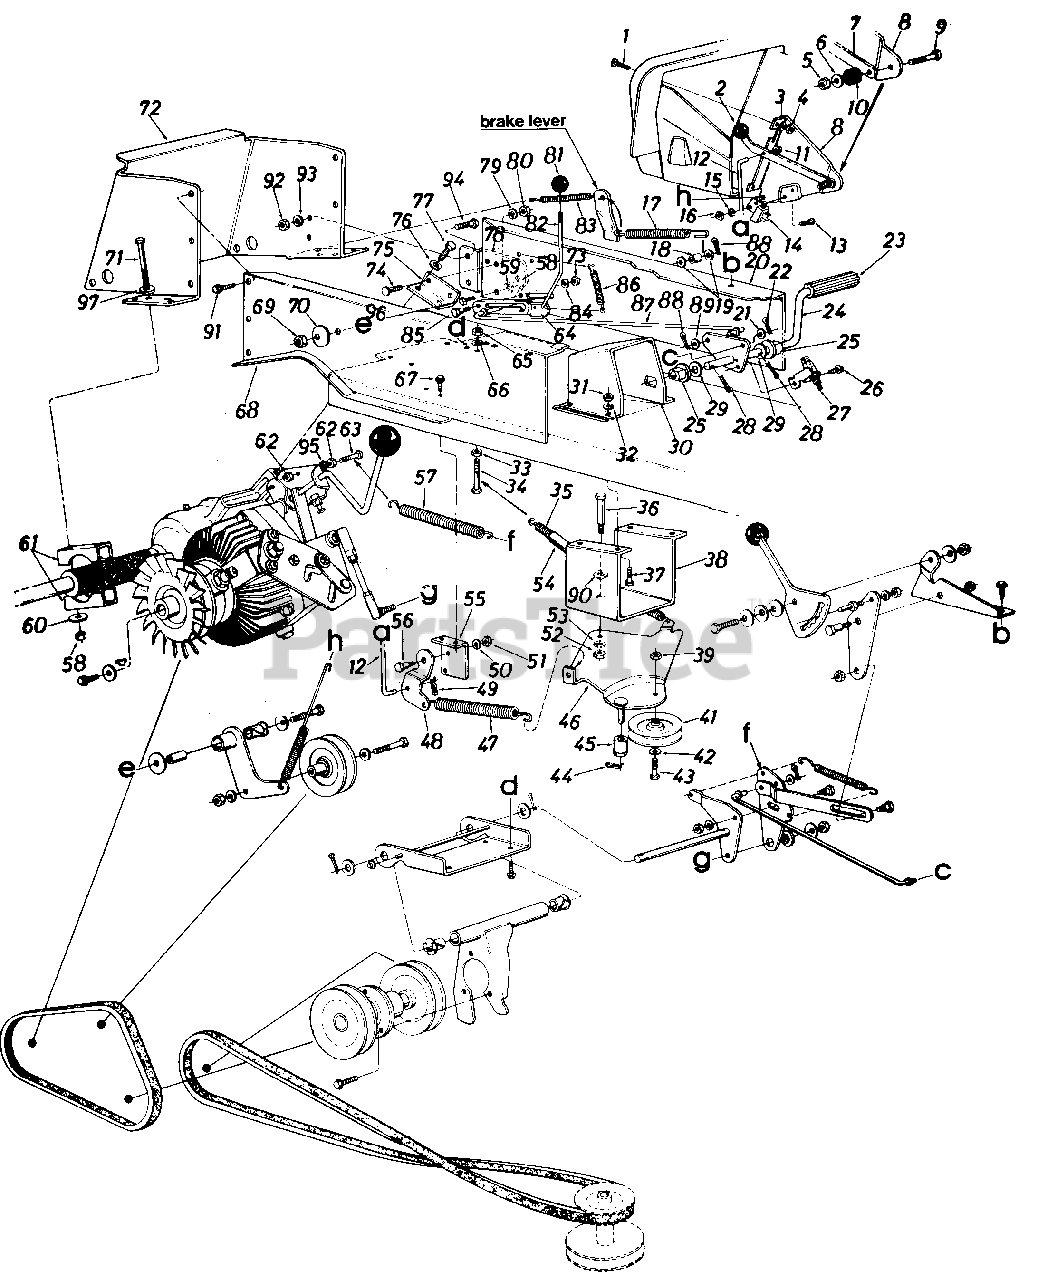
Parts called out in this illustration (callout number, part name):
1	Truss Mach. Scr. 1/4-20 x .50" Lg.
2	"T" Knob
4	Hex Sems Nut 1/4-20 Thd.
5	Hex Cent. L-Nut 1/4-20 Thd.
6	Fl-Wash. 1/4" I.D. x .75" O.D.
7	PTO Lever
8	Deck Clutch Control Brk't.
9	Hex Bolt 1/4-20 x .75" Lg.*
10	Rubber Wash. .33" I.D. x .87" O.D.
11	Push Cap 1/4" Rod
12	Deck Control Rod
13	Truss Mach. Scr. #10-24 x .50" Lg.*
14	Safety Switch
15	Ext. L-Wash. #10 Scr.
16	Hex Nut #10-24 Thd.*
17	Extension Spring .75" O.D. x 5.56" Lg.
18	Spacer.375" I.D. x .625" O.D. x .445" Lg.
19	Fl-Wash. .385" I.D. x .87" O.D.
20	Side Panel Upper Frame L.H.
21	Fl-Wash. .385" I.D. x .87" O.D.
22	Cotter Pin 3/32" Dia. x .75" Lg.*
23	Foot Pad
24	Foot Pedal Brk't. Ass'y.
25	Flange Brg. .630" I.D. x 1.25" O.D.
26	Hex Wash. Hd. S-Tap Scr. 1/4-20 x .50" Lg.
27	Safety Switch
28	Cotter Pin 1/8" Dia. x 1.00" Lg.
29	Fl-Wash. .640" I.D. x .24" O.D.
30	Steering Gear Support Ass'y.
31	Fl-Wash. .385" I.D. x .87" O.D.
32	L-Wash. 5/16" I.D.*
33	Hex Nut 1/4-20 Thd.*
34	Hex Bolt 1/4-20 x 2" Lg.*
35	Extension Spring .50" O.D. x 6.37" Lg.
36	Shld. Bolt 7/16" Dia. x .16" Lg.
37	Hex Bolt 5/16-18 x 1.00" Lg.*
38	Idler Mtg. Brk't. Deck
39	Hex L-Nut 3/8-16 Thd.
41	"V"-ld ler Pu I ley
42	Fl-Wash. 3/8" I.D.
43	Hex Bolt 3/8-16 x 1.75" Lg.*
44	Cotter Pin 5/16" Rod
45	Spacer
46	Idler Brk't. Ass'y.
47	Extension Spring Deck
48	Deck Control Pivot Brk't.
49	Cotter Pin 5/16" Rod
50	L-Wash. 5/16" I.D.
51	Hex Nut 5/16-18 Thd.
52	Hex Nut 5/16-18 Thd.
53	L-Wash. 5/16" I.D.
54	Convoluted Conduit .50" I.D. x 4" Lg.
55	Parking Brake Cam Mtg. Brk't.
56	Shld. Bolt 7/16" Dia. x .16" Lg.
57	Extension Spring
58	Hex Nut 3/8-16 Thd.
59	L-Wash. 3/8" I.D.
60	Bell-Wash. .39" I.D. x 1.13" O.D.
61	Rear Axle Brk't.
62	Hex Nut 5/16-24 Thd.
63	Hex Self-Tap Scr. 5/16-24 x 1.5" Lg.
64	Parking Brake Cam
65	Hex Nut 1/4-20 Thd.
66	L-Wash. 1/4" I.D.
67	Hex Wash. Hd. S-Tap Scr. 1/4-20 x .50" Lg.
68	Side Panel Upper Frame R.H.
69	Hex Nut 3/8-24 Thd.
70	Fl-Wash. .39" I.D. x 1.5" O.D.
71	Hex Bolt 3/8-16 x 3.50" Lg.
72	Hitch Plate
73	Hex Nut 3/8-16 Thd.
74	Rib Neck Scr. 3/8-24 x 1.0"
75	Mounting Brk't. Transaxle
76	L-Wash. 3/8" I.D.
77	Hex Bolt 3/8-16 x 1.00" Lg. Grade 5
78	Reinforcement Plate Frame
79	L-Wash. 3/8" I.D.
80	Hex Nut 3/8-24 Thd.
81	Gear Shift Knob
82	Parking Brake Link
83	Extension Spring .38" O.D. x 3.18" Lg.
84	Hex Nut 3/8-16 Thd.
85	Shld. Bolt .500" Dia. x .170
86	Extension Spring .38" O.D. x 3.18" Lg.
87	Rod Brake .38" Dia. x 19.3" Lg.
88	Cotter Pin 3/32" Dia. x .75" Lg.
89	Fl-Wash. .385" I.D. x .87" O.D.
90	Wave Wash.
91	Hex AB-Tap Scr. 5/16 x .75" Lg.
92	Hex Nut 5/16-24 Thd.
93	L-Wash. 5/16" I.D.
94	Hex Bolt 5/16-24 x .75" Lg.
95	L-Wash. 5/16" I.D.
96	Hex Bolt 3/8-16 x . 75" Lg.*
97	Fl-Wash. .385" I .D. x .87"
